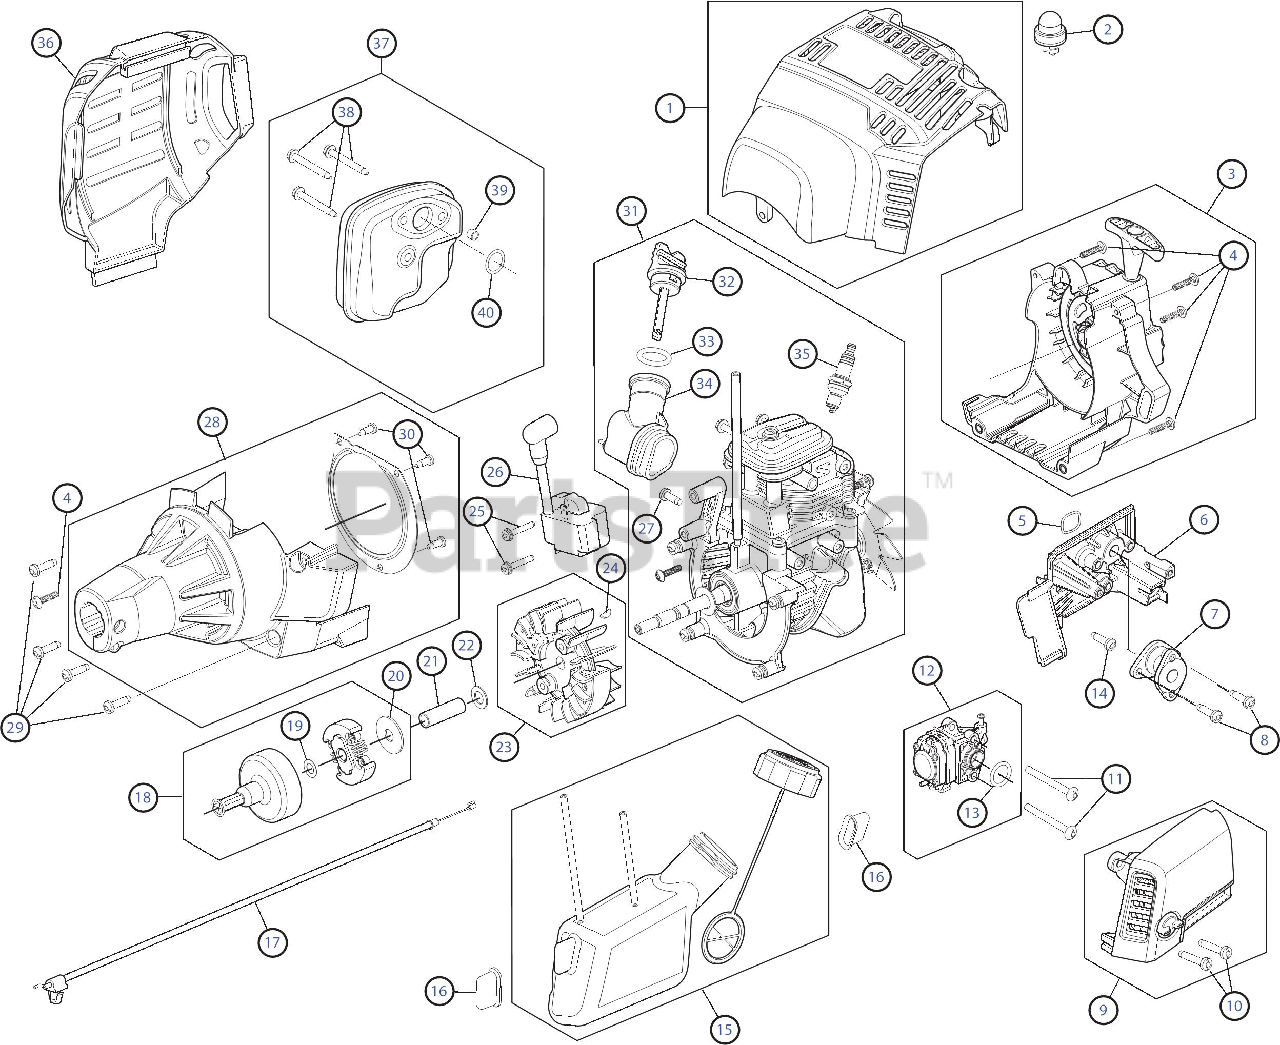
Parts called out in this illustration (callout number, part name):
1	Top Housing Assembly
2	Air Purge Primer
3	Starter Housing Assembly
6	Intake Port
7	Boot Assembly
9	Air Cleaner Assembly
12	Carburetor Assembly
14	Screw
15	Fuel Tank Assembly
16	Fuel Tank Pad
18	Clutch Assembly
19	Thrust Washer
20	Clutch Washer
21	Power Shaft Spacer
22	Thrust Washer
23	Flywheel Assembly
26	Module Assembly
28	Clutch Cover Assembly
31	Shortblock Assembly
32	Oil Fill Plug
34	Oil Fill Tube
35	Spark Plug
36	Muffler Housing
37	Muffler Assembly
38	Screw
39	Spacer
40	Muffler Gasket
